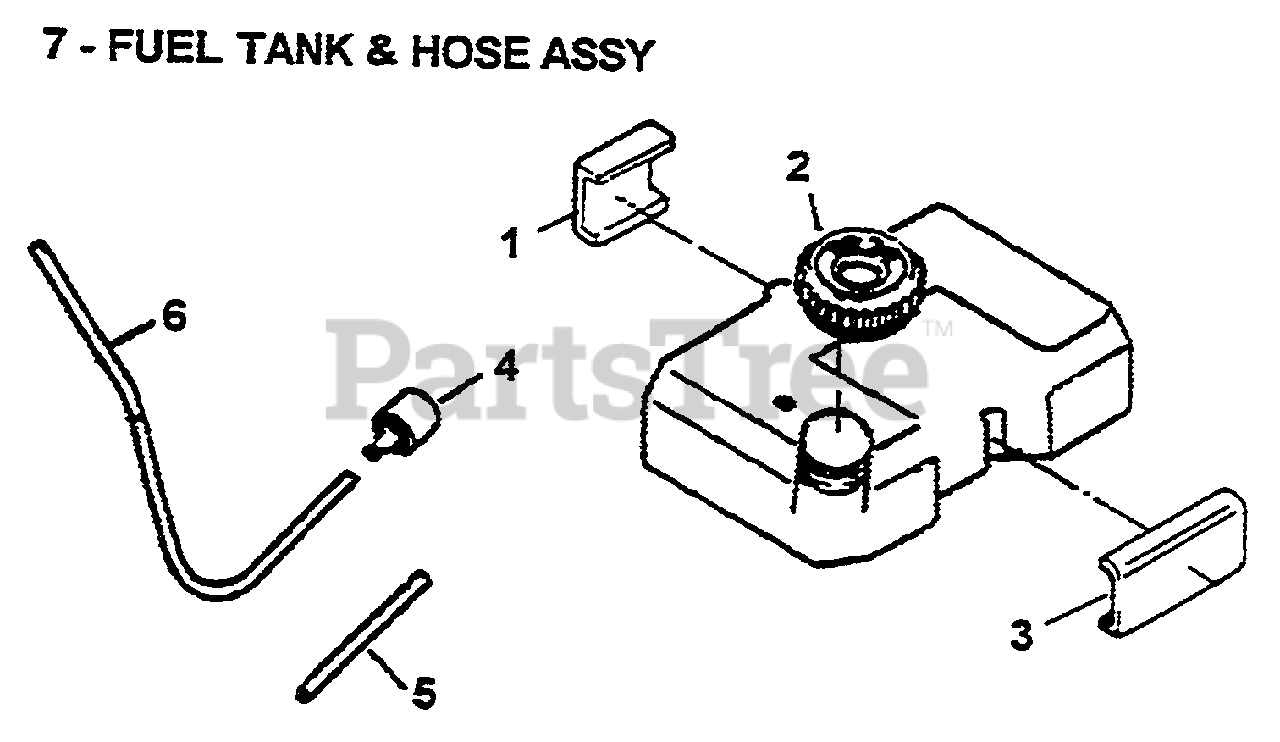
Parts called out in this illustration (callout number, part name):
4	FILTER, FUEL
5	HOSE, FUEL RETURN
6	HOSE, FUEL
7	FUEL TANK ASSY
